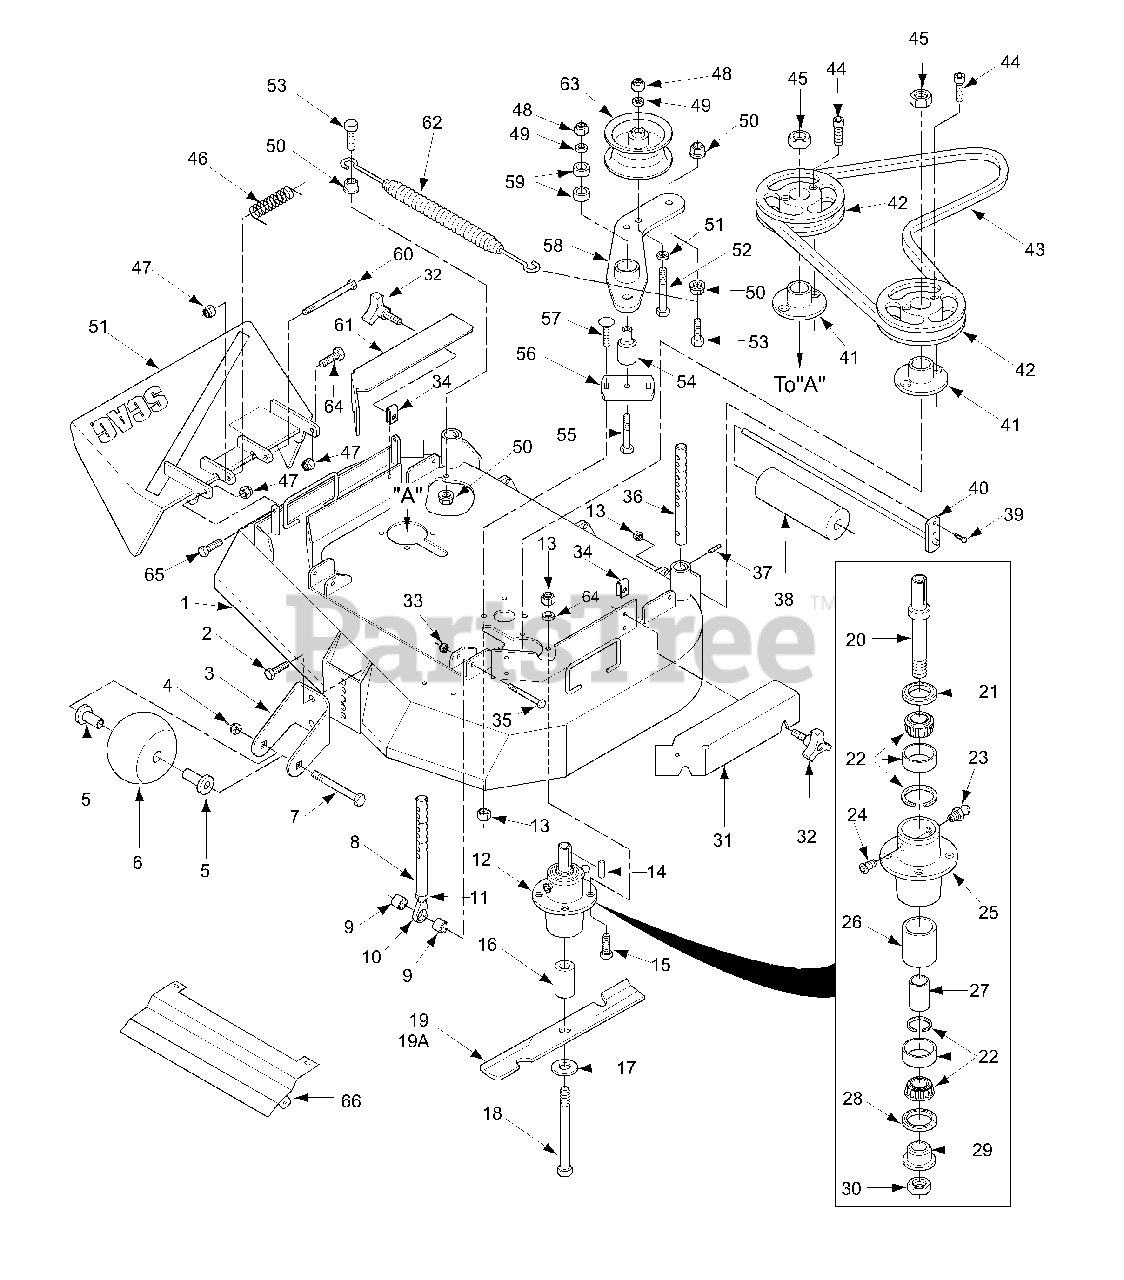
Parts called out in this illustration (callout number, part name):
1	Cutter Deck
2	Capscrew, 3/8-16 x 1.0" Serrated Flange Hex Hd
3	Bracket, Anti-Scalp Wheel
4	Lock Nut, 3/8-16 Center Lock
5	Bushing, 376 ID Oilite
6	Wheel, Anti-Scalp
7	Bolt, Carriage 3/8-16 x 4.0"
8	Pin Assy., Deck Adj.
9	Spacer, Deck Adjustment Pin
10	Rod End, Male 3/8-24 RH Thread
11	Nut, 3/8-24 Jam
12	Spindle Assembly
13	Nut, 5/16-18 Serrated Flange
14	Key,1/4 x 1/4 x 2.0"
15	Bolt, Hex Head 5/16-18 x 1.25"
16	Spacer, Spindle
17	Flatwasher, 5/8 W
18	Bolt, Hex Head 5/8-11 x 9.50"
19	Cutter Blade, 18"
19A	Cutter Blade, 18" Hi Lift
20	Spindle Shaft
21	Seal, Cutter Spindle Top
22	Tapered Bearing Set (Two Bearings W/Race)
23	Grease Fitting
24	Relief Fitting, Cutter Spindle
25	Spindle Housing
26	Spacer, Outside
27	Spacer, Inside
28	Seal, Cutter Spindle Bottom
29	Spindle Bushing
30	Nut, Spindle
31	Belt Cover, LH
32	Wing Nut, 3/8-16
33	Nut, 3/8-16 Elastic Stop
34	U-Nut, 3/8-16
35	Bolt, Hex Head 3/8-16 x 2.50"
36	Pin, Deck Adj. Rear
37	Pin, Sloted Spring 3/16 x 1.50"
38	Guide, Roller
39	Bolt, Hex Head 5/16-18 x 1.0"
40	Roller Shaft
41	Tapered Hub
42	Pulley
43	Belt, Cutter Deck
44	Capscrew, Socket Head. 1/4-20 x 1.375"
45	Hex Nut, 5/8-11
46	Spring, Chute Return
47	Hex Nut, 5/16-18 Elastic Stop
48	Hex Nut, 3/8-16 Elastic Stop
49	Flatwasher, 3/8 (.938 x .391 x .105)
50	Nut, 3/8-16 Serrated Flange
51	Discharge Chute
52	Capscrew, Hex Head 3/8-16 x 3.75"
53	Capscrew, Hex Head 3/8-16 x 1.50"
54	Pivot, Idler - Long
55	Capscrew, Hex Head 38/16 x 3.25"
56	Base, Idler Pivot
57	Bolt, Carriage 5/16-18 x 1.0"
58	Idler Arm Weldment
59	Ball Bearing
60	Bolt, Hex Head 5/16-18 x 4.25"
61	Belt Cover, RH
62	Spring, Deck Idler
63	Pulley, Idler
64	Bolt, Hex Head 5/16-18 x 1.5"
65	Bolt, Hex Head 5/16-18 x 1.75"
66	Heatshield
